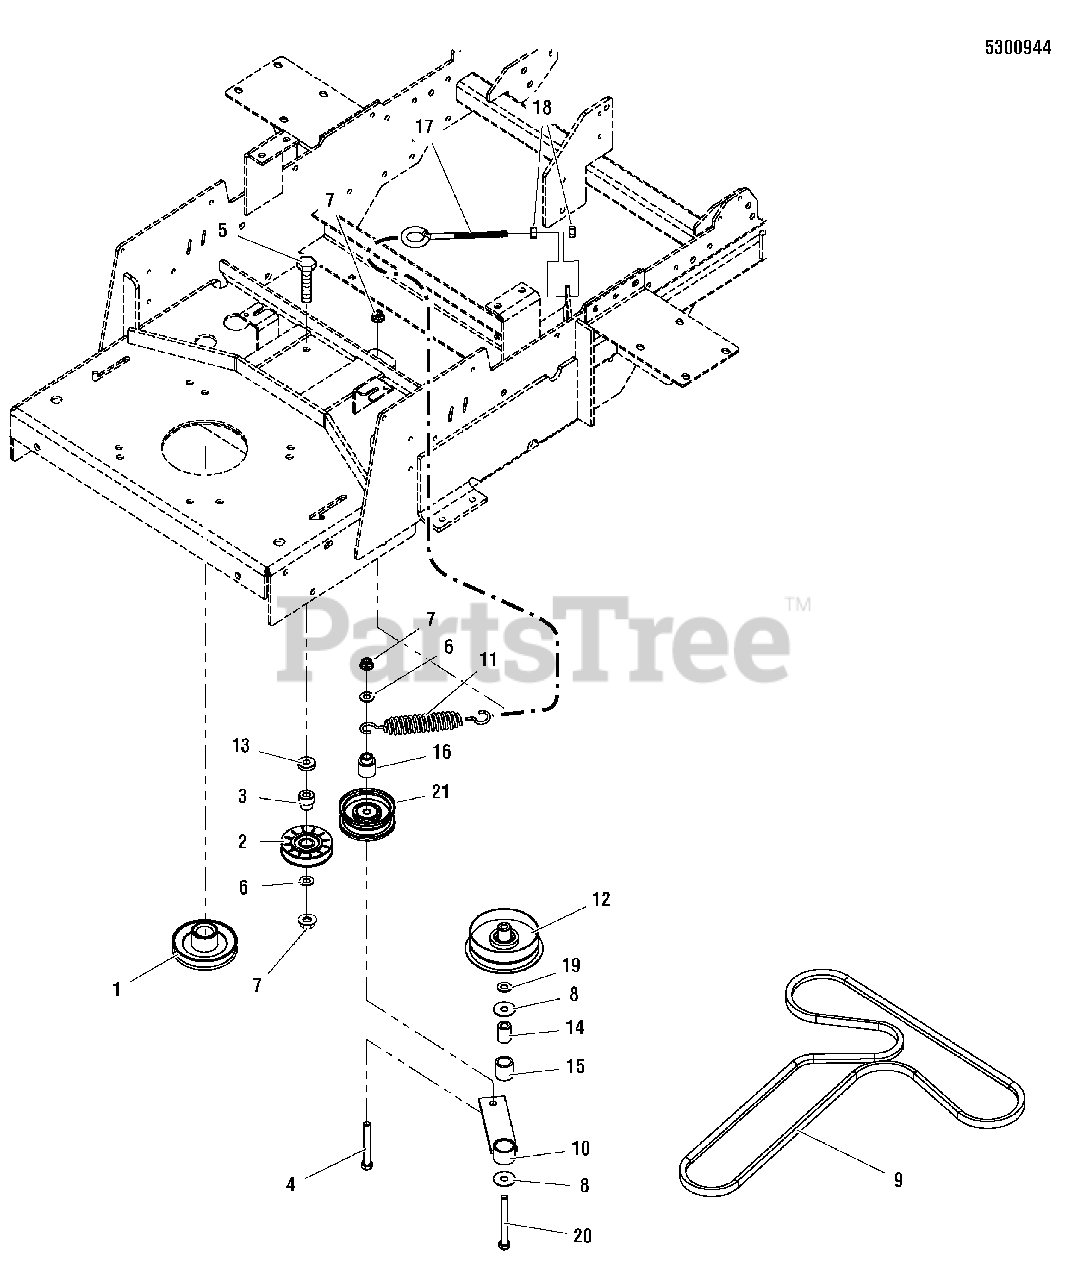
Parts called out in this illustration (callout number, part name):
1	PULLEY, CRANKSHAFT
2	IDLER PULLEY
3	SPACER, HYDRO PULLEY
4	BOLT, 3/8-16 X 3" GD5 CZ
5	BOLT, 3/8-16 X 2, GD5, CZ
6	WASHER, 3/8 SAE
7	NUT, 3/8-16 HEX NYLOCK FLANGE
8	WASHER, 3/8 FENDER
9	BELT, 79.46 EL, HYDRO DRIVE
10	WELD, IDLER, PUMP DRIVE - RED
11	SPRING, EXTENSION, SWIVEL END
12	PULLEY, IDLER, SINGLE FLANGE, 4" OD
13	SPACER, .39 X 1.00 X .25
14	SPACER, .39 X .75 X 1.06
15	BUSHING, BRASS, 3/4 X 1 X 1
16	SPACER, SHOULDER
17	EYE BOLT, 3/8-16 X 5, 2.88THRD, 1EYE, CZ
18	NUT, 3/8-16 HEX
19	WASHER, 3/8 GD. 9 FLAT
20	BOLT, 3/8-16 X 3-1/2" GD5 CZ
21	PULLEY, IDLER, FLAT, 2.75 DIA X .376 ID
